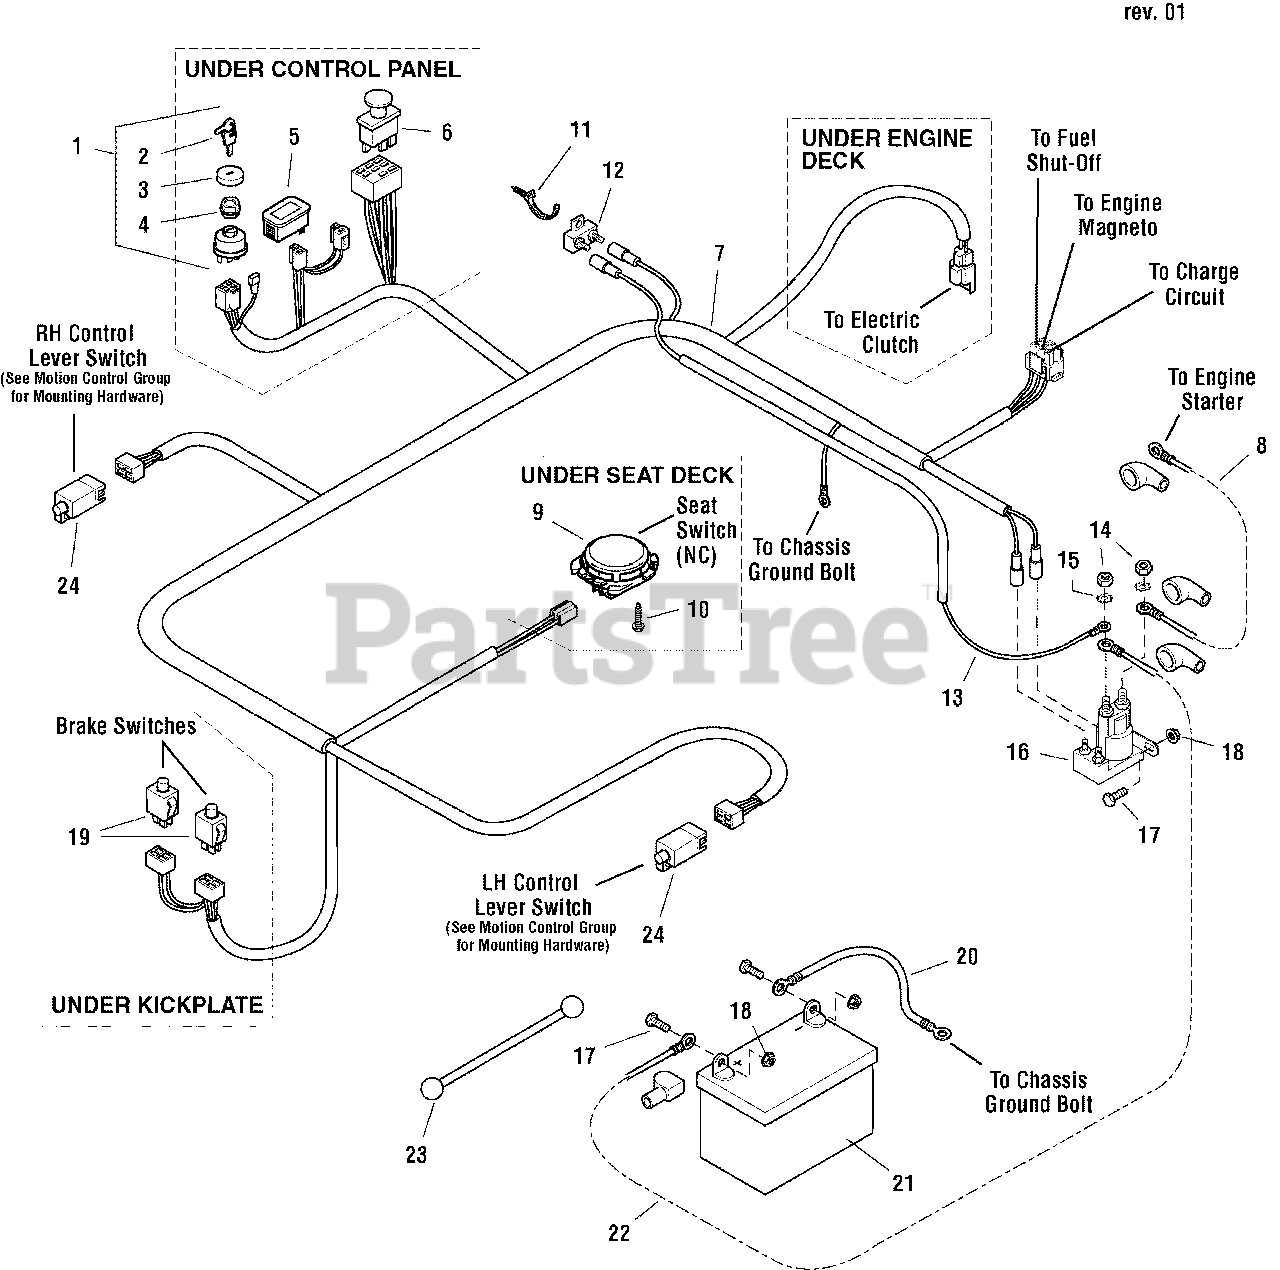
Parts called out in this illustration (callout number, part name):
1	SWITCH, IGNITION, 6 POST
1	SWITCH, Ignition (No Keys/HDWR)
2	KEY, IGNITION MOLDED SET
2	KEYS, Blister Pk (KIDS+MWRS DON'T MIX) (set of two, one coated)
3	COVER, PLASTIC, SNAP ON
4	NUT, HEX FLANGE 5/8-32 IGN SW DIE CAST
5	HOUR METER, DIGITAL
6	SWITCH, PTO
7	MAIN HARNESS ASSEMBLY
8	CABLE, #6 X 15" LONG, RING TERMINAL
9	SWITCH, NC, W/ TWIST-IN BASE
9	SWITCH, NC, W/ BOLT-IN BASE
10	BOLT, HEX WASHER HEAD PLASTITE, 1/4 X 1/2
11	CABLE TIE, PUSH MOUNT
12	CIRCUIT BREAKER, 20A
13	CRICUIT BREAKER WIRE ASSEMBLY
14	NUT, HEX JAM, 5/16-24
15	WASHER, LIGHT LOCK, 5/16
16	SOLENOID
17	BOLT, 1/4-20 X 3/4
18	NUT, HEX SERRATED FLANGE, 1/4-20
19	SWITCH, PLUNGER, NO/NC, SNAP IN
20	CABLE, #6 X 22" LONG, RING TERMINAL
22	CABLE, #6 X 30" LONG, RING TERMINAL
23	STRAP, BATTERY, 14 LONG, RUBBER
24	SWITCH, PLUNGER, NO/NC
